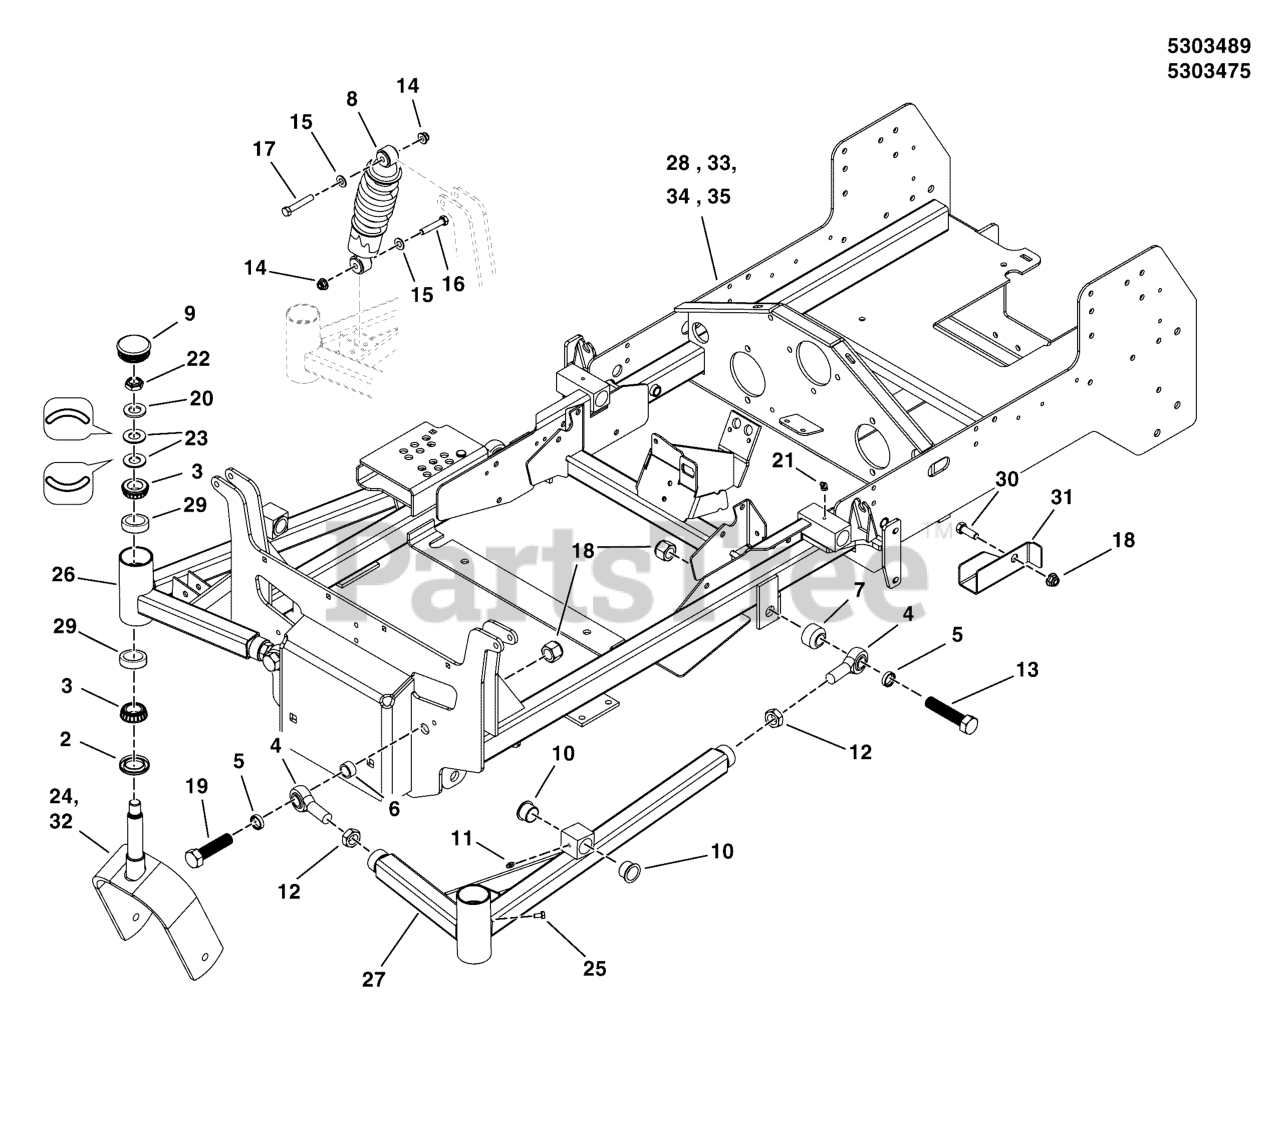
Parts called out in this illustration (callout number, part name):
2	SEAL, GREASE
3	BEARING, TAPERED ROLLER, 1
4	BALL JOINT, 3/4-16, MALE
5	SPACER, .76 X 1.00 X .25
6	SPACER, .76 X 1.00 X .50
7	SPACER, .75 X 1.50 X 1.00
8	SHOCK ABSORBER
9	CAP, GREASE, LOW PROFILE
10	BUSHING, 1.00X1.13X.75, PLA
11	GREASE FITTING, 1/4-28, 90 DEGREE
12	NUT, 3/4-16 HEX JAM
13	BOLT, 3/4-16 X 3-1/2 YZ GD5
14	NUT, 3/4-16 HEX NYLON LOCK
15	WASHER, 3/8 SAE
16	BOLT, 3/8-16 X 2, GD5, CZ
17	BOLT, 3/8-16 X 2-1/4" GD5 CZ
18	NUT, 3/8-16 HEX NYLOCK FLANGE
19	BOLT-3/4-16 X 3 YZ GD5
20	WASHER, 3/4 SAE
21	GREASE FITTING, 45 DEGREE
22	NUT, 3/4-16, HEX JAM NYLON LOCK
23	WASHER, BELLEVILLE - 1.500 X .755
24	WELD, CASTER YOKE -RED
25	BOLT, 1/4-28 X 1/2, GD5 YZ
26	WELD, FRONT A-ARM, RH, IS2500 - RED
27	WELD, FRONT A-ARM, LH, IS2500 - RED
28	WELD, MAIN FRAME, IS2500Z, 52 - RED
29	BEARING CUP (SV)
30	BOLT, 3/8-16 X 3/4,ALLEN BUTTON
31	TRAY, WIRE HARNESS, IS2500 - RED
32	WELD, CASTER YOKE - RED
33	WELD, MAIN FRAME, IS2500Z, 61 - RED
34	WELD, MAIN FRAME, IS2500Z, 52 - RED
35	WELD, MAIN FRAME, IS2500Z, 61 - RED
